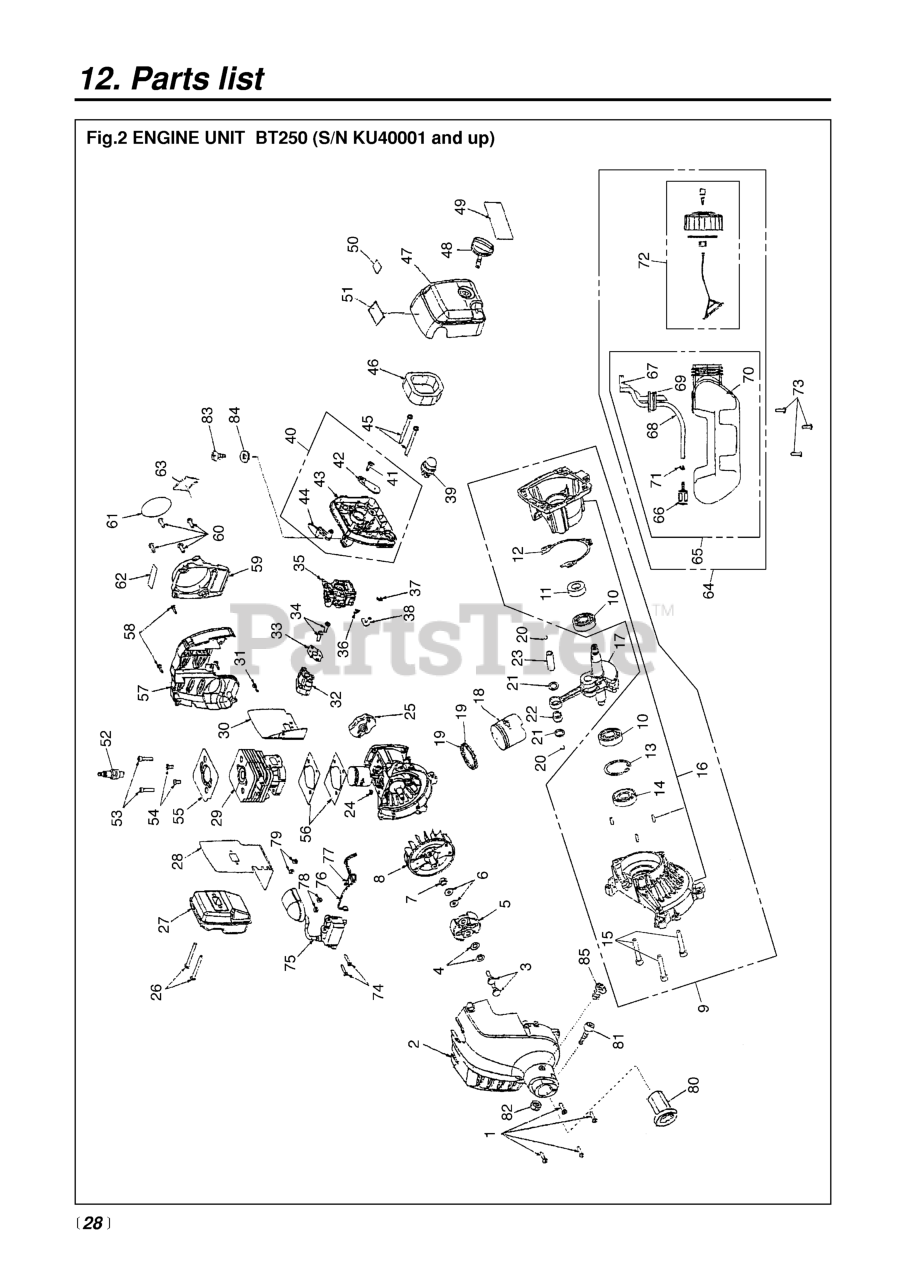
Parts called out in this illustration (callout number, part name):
1	SCREW
2	FRONT HOUSING
3	SCREW, CLUTCH
4	WASHER, CURVED
5	CLUTCH ASSY
6	WASHER, PLAIN
7	NUT
8	ROTOR
9	CRANKCASE & SHAFT ASS
10	BEARING
12	GASKET, CRANKCASE
13	RING
14	SEAL
16	CRANKCASE ASS
17	CRANKSHAFT ASS
18	PISTON
19	RING, PISTON
20	CLIP RING
21	WASHER
22	NEEDLE BEARING
23	WRIST PIN
25	PULLEY ASS
26	BOLT, MUFFLER
27	MUFFLER & ARRESTER
28	MUFFLER GASKET
29	CYLINDER
30	GASKET, INSULATOR
31	SCREW, TORX
32	INSULATOR
33	GASKET, CARBURETOR
34	SCREW, TORX
35	CARBURETOR
36	CLIP, HOSE
37	CLIP, HOSE
38	PLASTIC RUBBER, TUBING
39	PRIMER ASS
40	CHOKE LEVER & PLATE ASS
41	SCREW, TORX
42	CHOKE PLATE
43	CARBURETOR PLATE
44	CHOKE LEVER
45	BOLT, CARBURETOR
46	ELEMENT
47	COVER ASS
48	KNOB
50	LABEL, START
51	LABEL, CAUTION
52	SPARK PLUG
53	CAP SCREW
54	SCREW, TORX
55	PLATE FIN
56	GASKET, CYLINDER
57	REAR HOUSING
58	SCREW, TORX
59	RECOIL ASSY
60	SCREW, TORX
61	LABEL, STARTER
62	LABEL, E START
63	LABEL, EMISSION
64	TANK & CAP ASS
65	TANK ASS
66	FILTER
67	PIPE RETURN
68	PIPE FUEL
69	TANK GROMMET
70	TANK
71	CLIP, HOSE
72	CAP ASS
73	BOLT, TORX
74	BOLT, TORX
75	COIL & BOLT ASS
76	LEAD ASS
77	LEAD ASS
78	SPACER
80	CUSHION
81	BOLT, M6 x 30
83	SCREW
84	WASHER
85	SCREW
